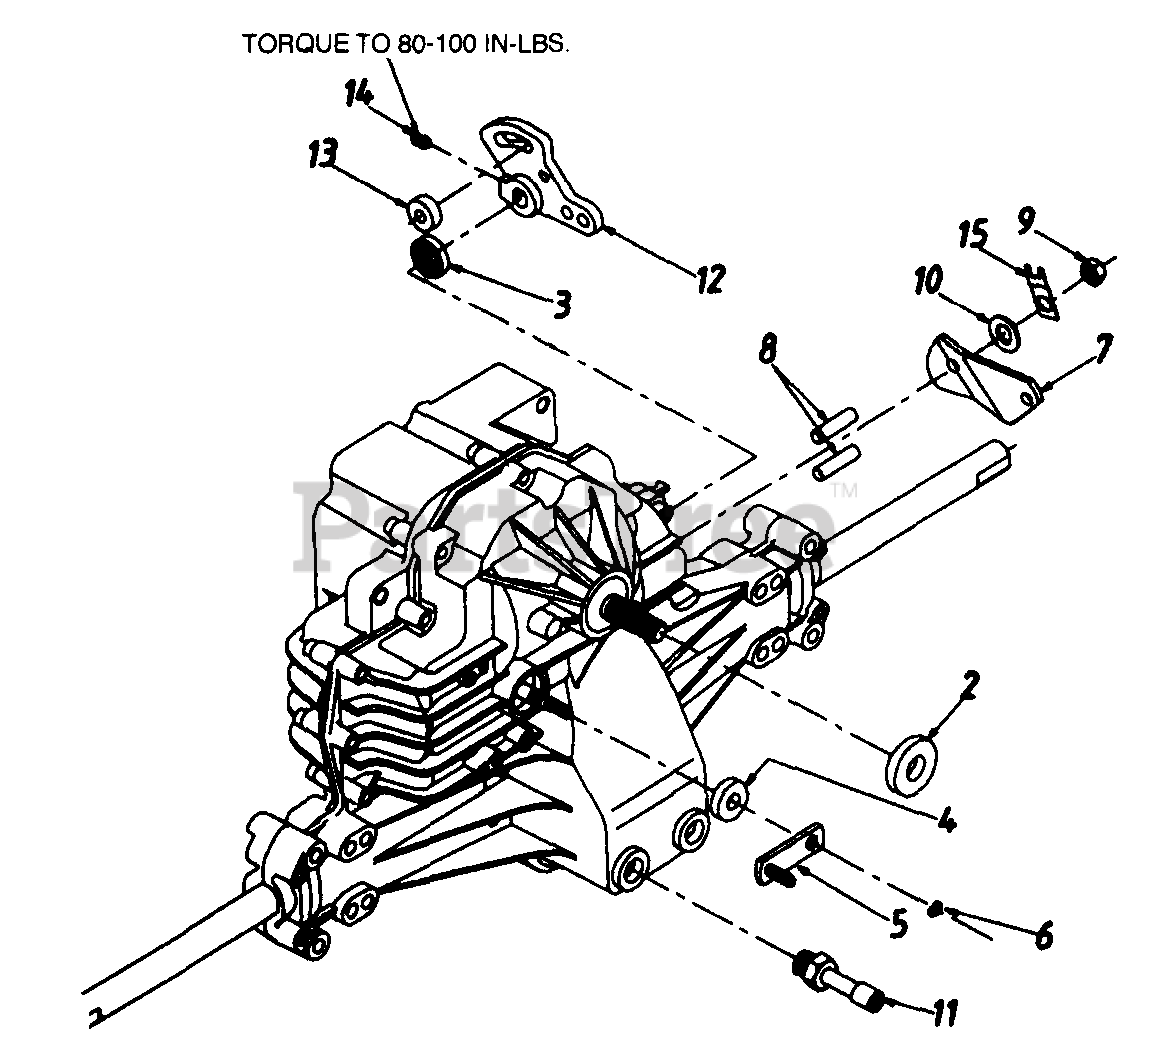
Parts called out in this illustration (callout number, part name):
4	Seal - Lip 10 x 25 x 7
5	Arm - Bypass
6	Ring - Retaining
7	Arm - Actuating
8	Pin - Actuating
9	Nut - Hex Lock 5/16-24 UNJC
10	Washer 7/16" x 7/8" x .060"
11	Breather Ass'y.
12	Arm - Control
13	Puck - Dampener
15	Strap, Locking
